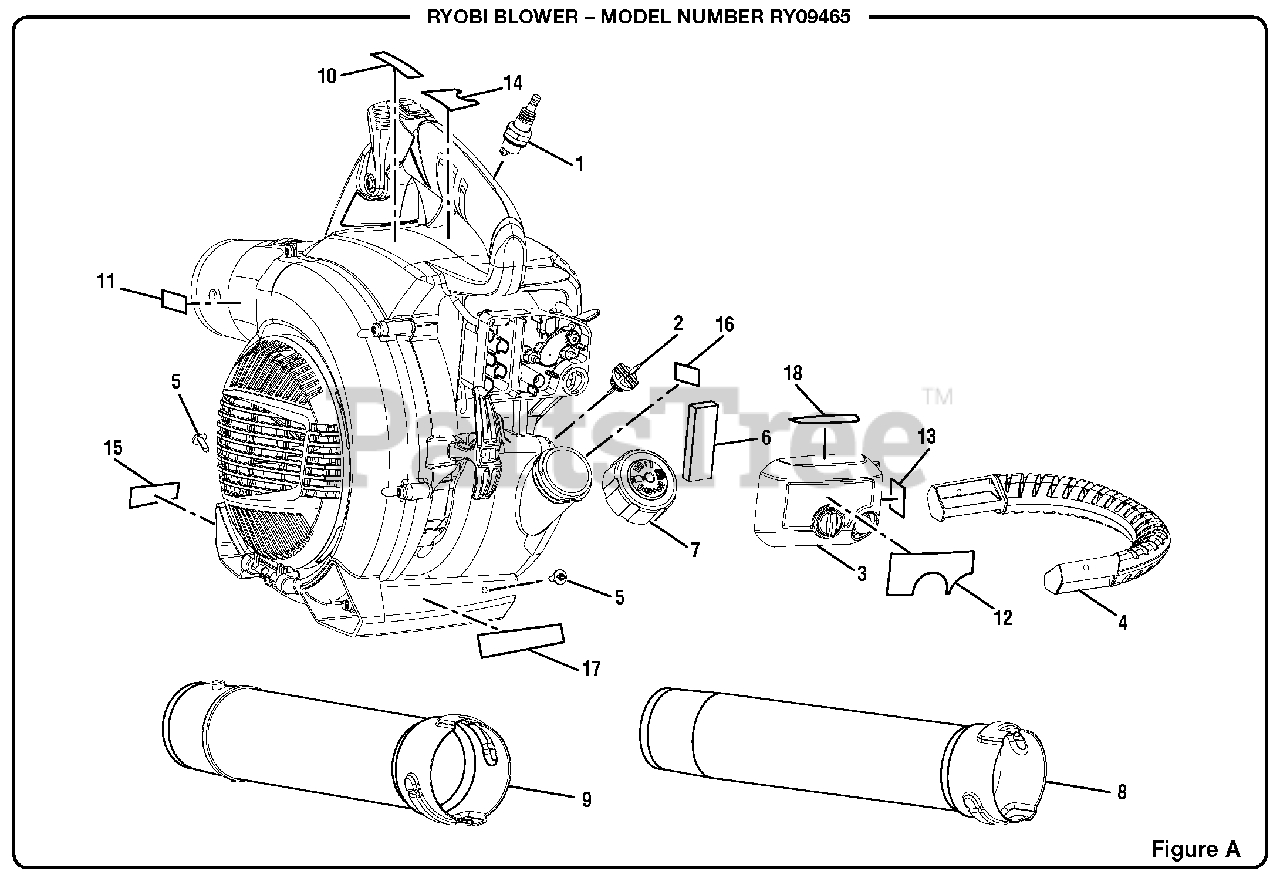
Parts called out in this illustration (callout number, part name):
1	Spark Plug (RY4C)
2	Oil Fill Cap w/Dipstick
3	Air Filter Cover
5	Screw (10-14 x 1/2 in.)
7	Fuel Cap Assembly
8	Sweeper Nozzle
9	Upper Blower Tube
10	Warning Label
11	Logo Label
12	Starting Label
13	Run/Start Label
14	Logo Label
15	Combustion Warning Label
16	Add Oil Label
17	No Mix Label
18	Stop Label
